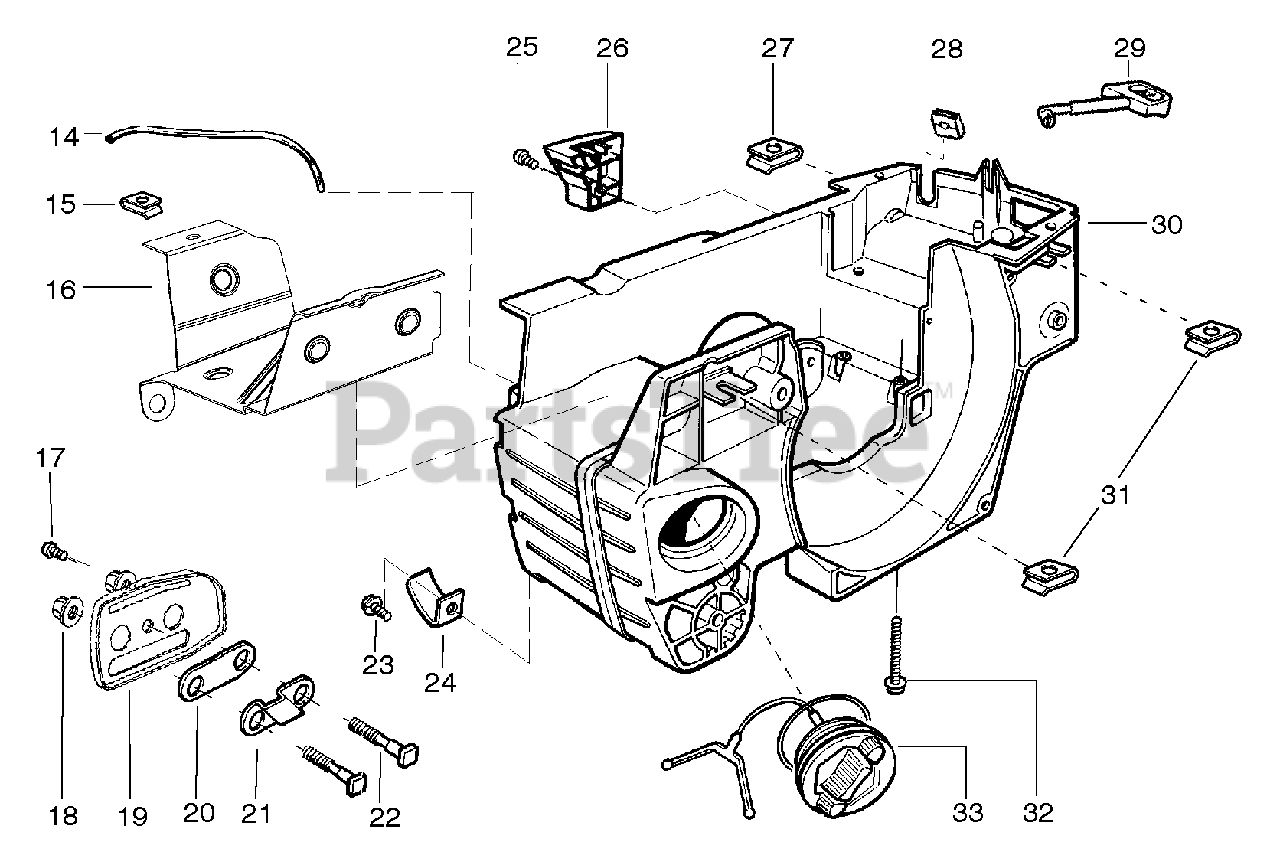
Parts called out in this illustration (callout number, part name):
14	Tube-Oil Vent
15	Clip-Retainer
16	Shield-Heat
17	Screw
21	Plate-Bar Stud
24	Chain Catcher
27	Nut-Type "U" Speed
29	Lever-Choke
30	Kit - Chassis Ass’y.
31	Nut-Type "U" Speed
33	Assy.- Oil Tank Cap
